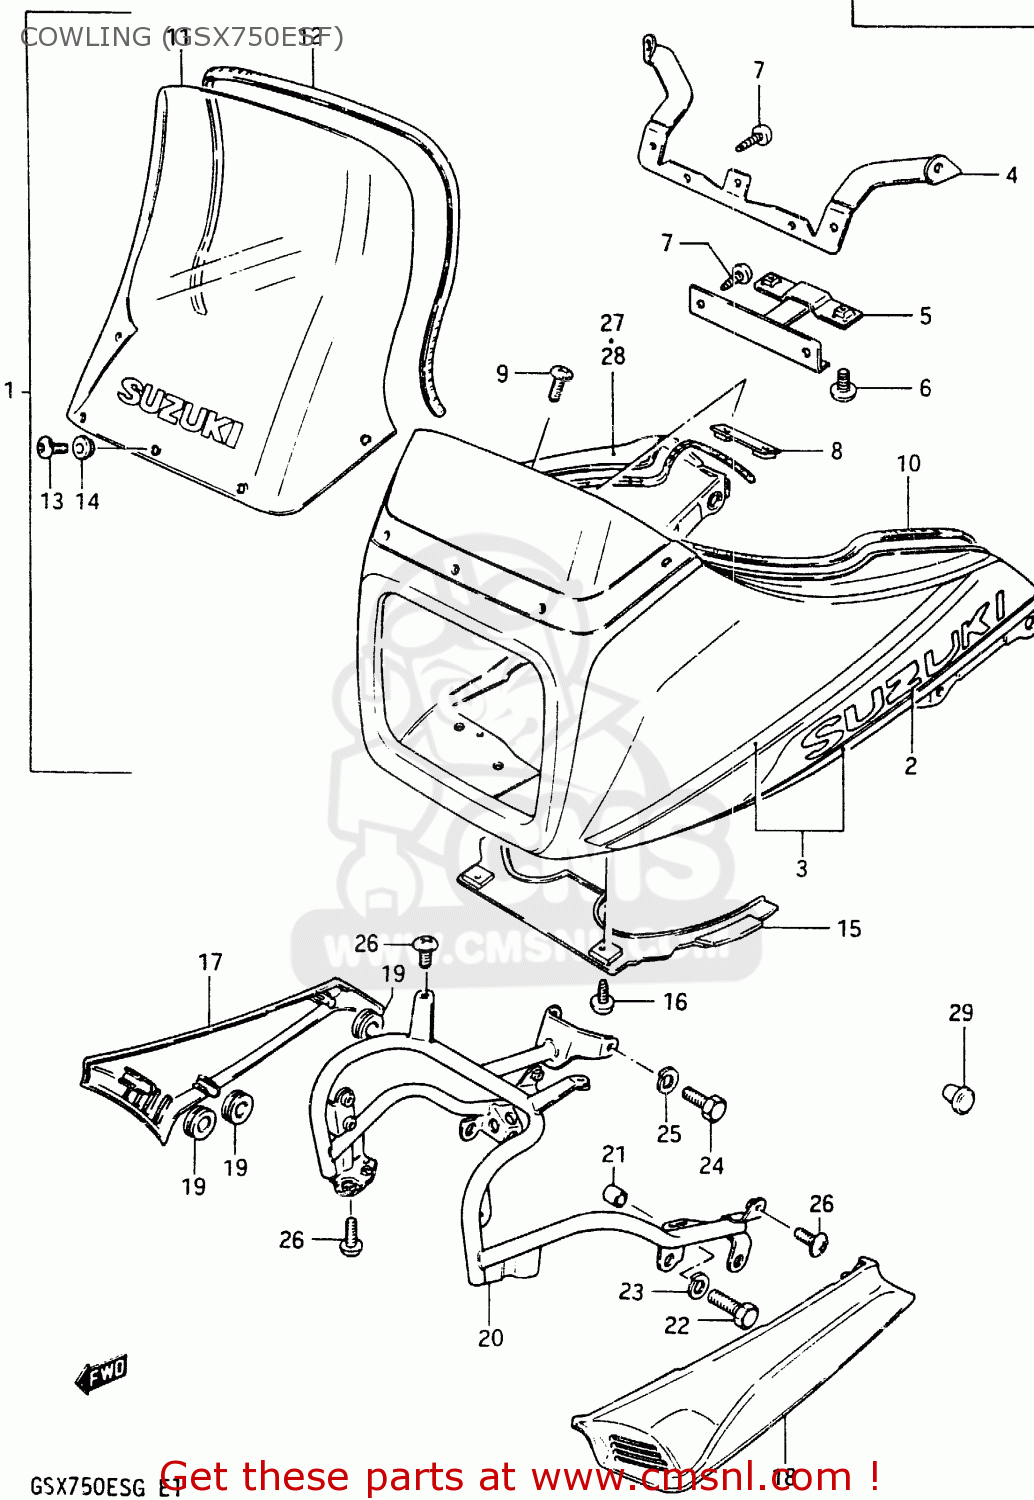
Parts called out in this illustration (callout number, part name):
1	COWLING ASSY (WHITE/RED)
2	EMBLEM
3	TAPE SET
4	BRACE,COWLING,UPPER
5	BRACE,COWLING,LOWER
6	SCREW
7	SCREW
8	BRACE
9	SCREW
10	MOLDING,FUEL TANK
11	WINDOW
12	MOLDING
13	SCREW
14	CUSHION
15	COVER,COWLING,LOWER
16	SCREW
17	COVER,COWLING,RIGHT
18	COVER,COWLING,LEFT
19	CUSHION
20	BRACE,COWLING
21	SPACER,COWLING
22	BOLT
23	WASHER,LOCK,8.
24	BOLT
25	WASHER,LOCK,8.
26	SCREW 6X12
27	TAPE,RIGHT
28	TAPE,LEFT
29	PLUG
